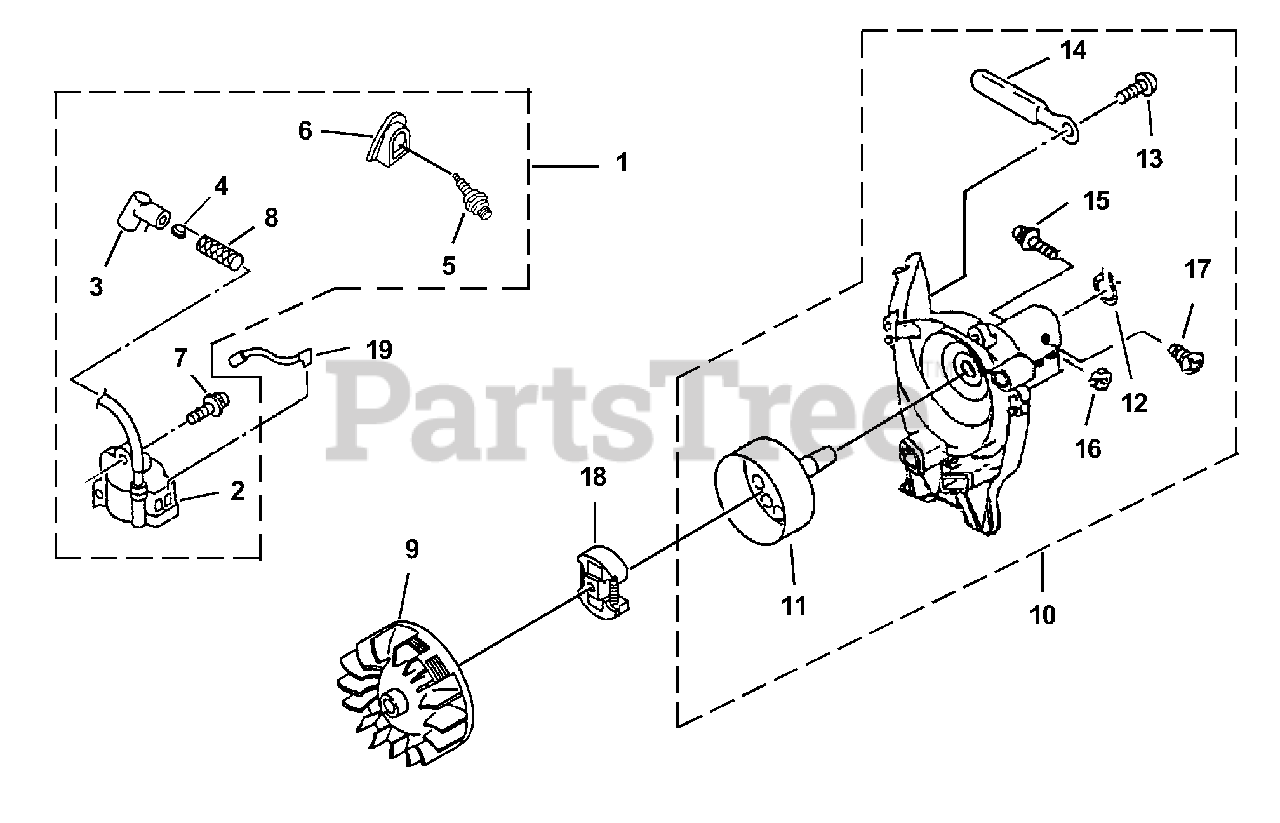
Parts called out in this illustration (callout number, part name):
1	IGNITION KIT
2	MODULE-Ignition
3	CAP-Plug
4	SPRING-Plug Cap
5	SPARK PLUG
6	COVER-Plug Cap
7	SCREW (M4 x 20 W SW)
10	CLUTCH HOUSING
11	CLUTCH DRUM
12	SNAP RING-Outer
13	SCREW-Self Tapping
14	CLAMP-Wire
15	SCREW ASSY. (M5 X 30 W SW)
16	NUT (M5)
17	SCREW-Tapping
